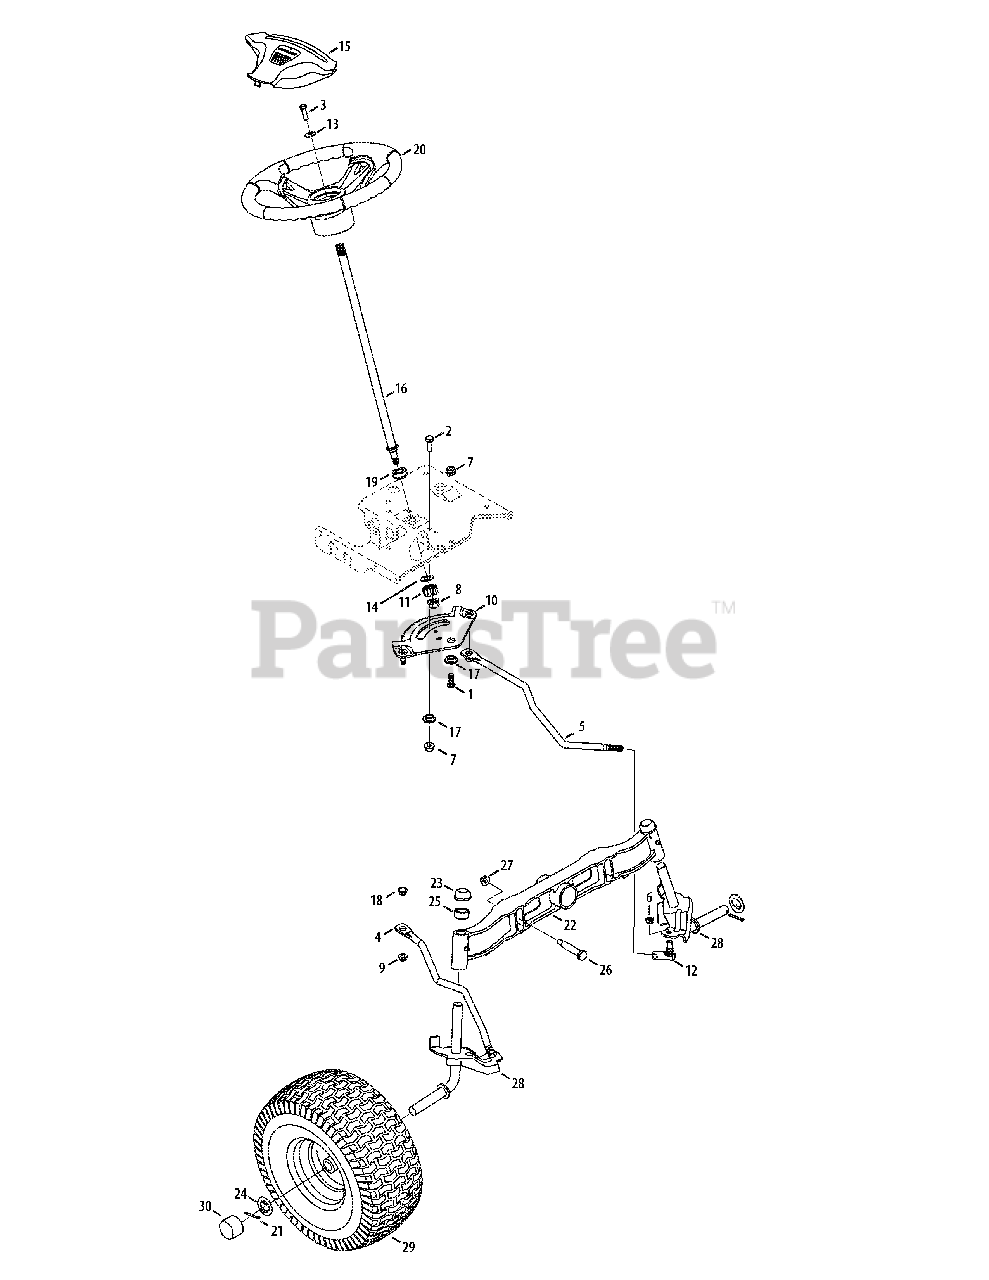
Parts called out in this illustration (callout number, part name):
1	Hex Cap Screw, 3/8-16, 1.00
2	Hex Cap Screw, 3/8-16, 1.00, Gr5, Std
3	Self-tapping Screw, 5/16-18 x .75
4	Link, Drag, RH
5	Link, Drag, LH
6	Nut, Hex, 3/8-24, Gr5
7	Nut, Nylon Lock, 3/8-16
8	Nut, Flange Lock, 7/16-20
9	Nut, Flange Lock, 5/16-18
10	Gear, Steering, 11/90 Ratio
11	Gear, Pinion, Steering
12	Ball Joint, 7/16-20
13	Washer, Flat, .406 x .875 x .105
14	Washer, Flat, .510 x 1.120 x .060
15	Cover, Steering Wheel
16	Shaft, Steering, .625 OD x 25.00 Lg
17	Spacer, Shoulder, 1.00 x .38 x .38
18	Bushing, Plastic, .380 ID
19	Bearing, Hex Flange, 5/8
20	Wheel, Steering, Three Spoke
21	Pin, Cotter, 5/32, 1.25
22	Axle, Pivot Bar, Cast
23	Push Cap, .75
24	Washer, Flat, .781 x 1.590
25	Spacer, .71 x .125 x .56
26	Bolt, Shoulder, 3/8-16 x .500 x 2.38
27	Nut, Jam, 3/8-16, Grf.
28	Axle Ass’y, LH .750 Dia.
28	Axle Ass’y, RH .750 Dia.
